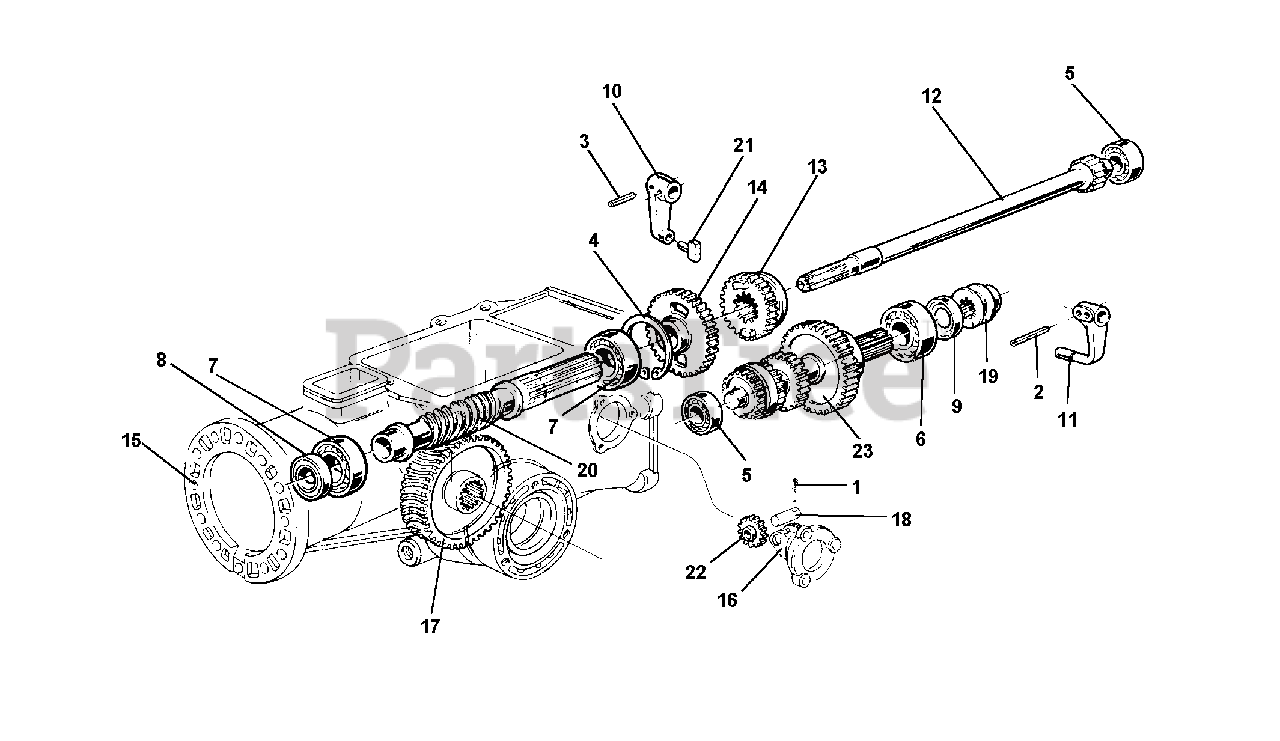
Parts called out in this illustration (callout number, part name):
1	PIN, LOCKING 2.5 X 22 DIN 1481
2	LOCKING PIN 4 X 20 SPIRAL
3	LOCKING PIN 4 X 24 SPIRAL
4	CIRCLIP, INTERN D 52
5	BEARING 15 X 35 X 11 6202
6	BEARING 20 X 47 X 14 6204
7	BEARING 25 X 52 X 15 6205
8	SEAL, OIL 15 X 40 X 10 STANDARD
9	SEAL, OIL 20 X 35 X 7 STANDARD
10	LEVER, SPEED CHG SLDG GR
11	SLIDE LEVER
12	CLUTCH SHAFT
13	SLIDING GEAR
14	I SPEED WHEEL
15	HOUSING BODY
16	REVERSE SPEED FLANGE
17	GEAR Z 49, LH MOTOR MOWER
22	REVERSE SPEED GEAR
23	P.T.O. SHAFT
